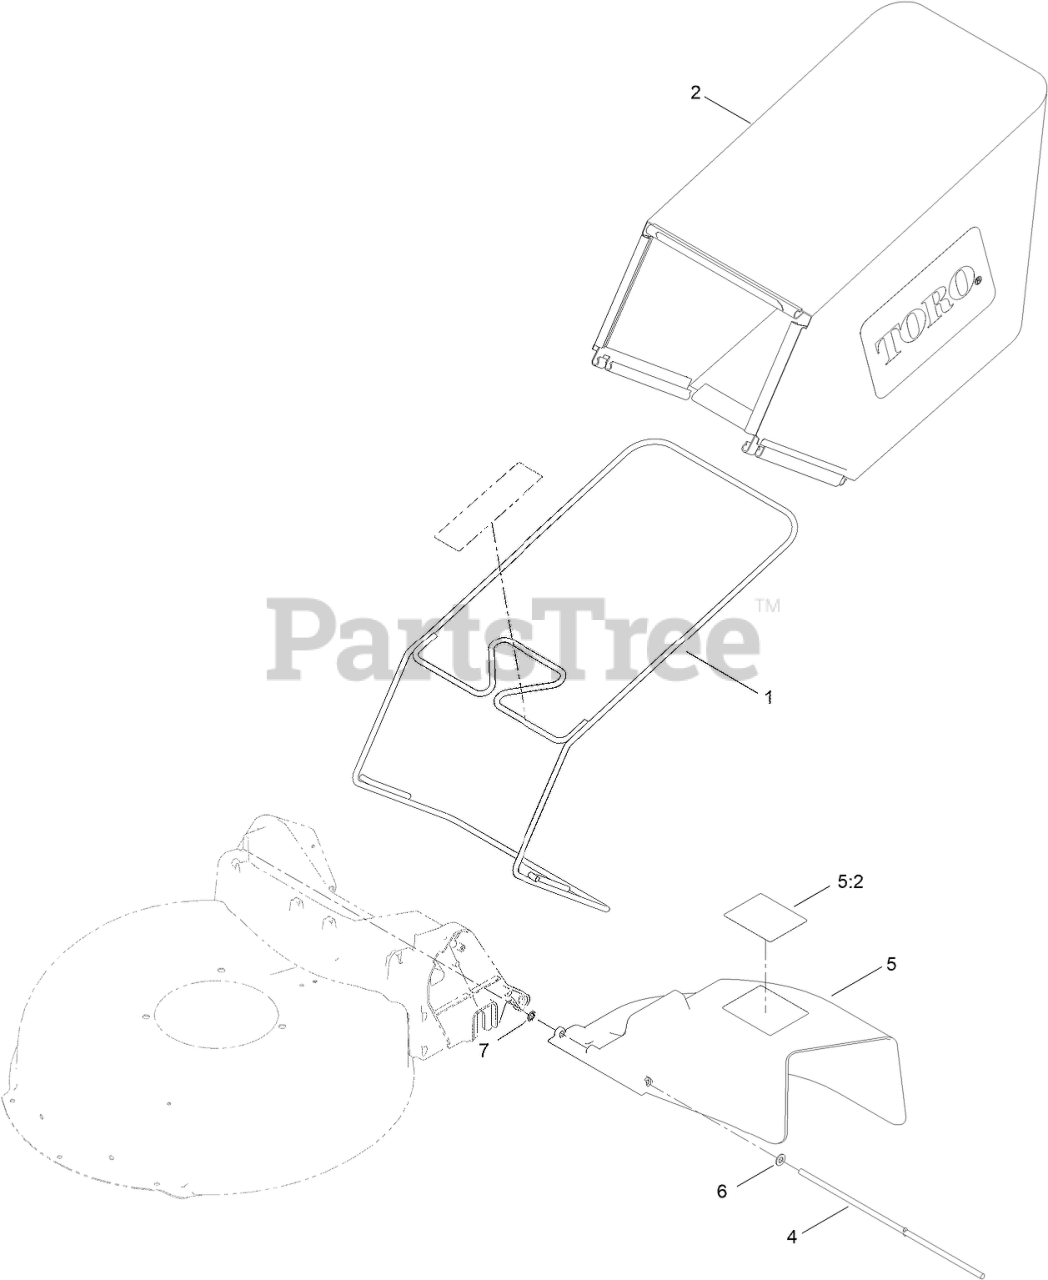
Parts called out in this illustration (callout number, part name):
1	FRAME-BAG
2	BAG-GRASS, ASM
5	DEFLECTOR-CHUTE
5:2	DECAL-WARNING
6	WASHER-PLAIN
7	RING-RETAINING
